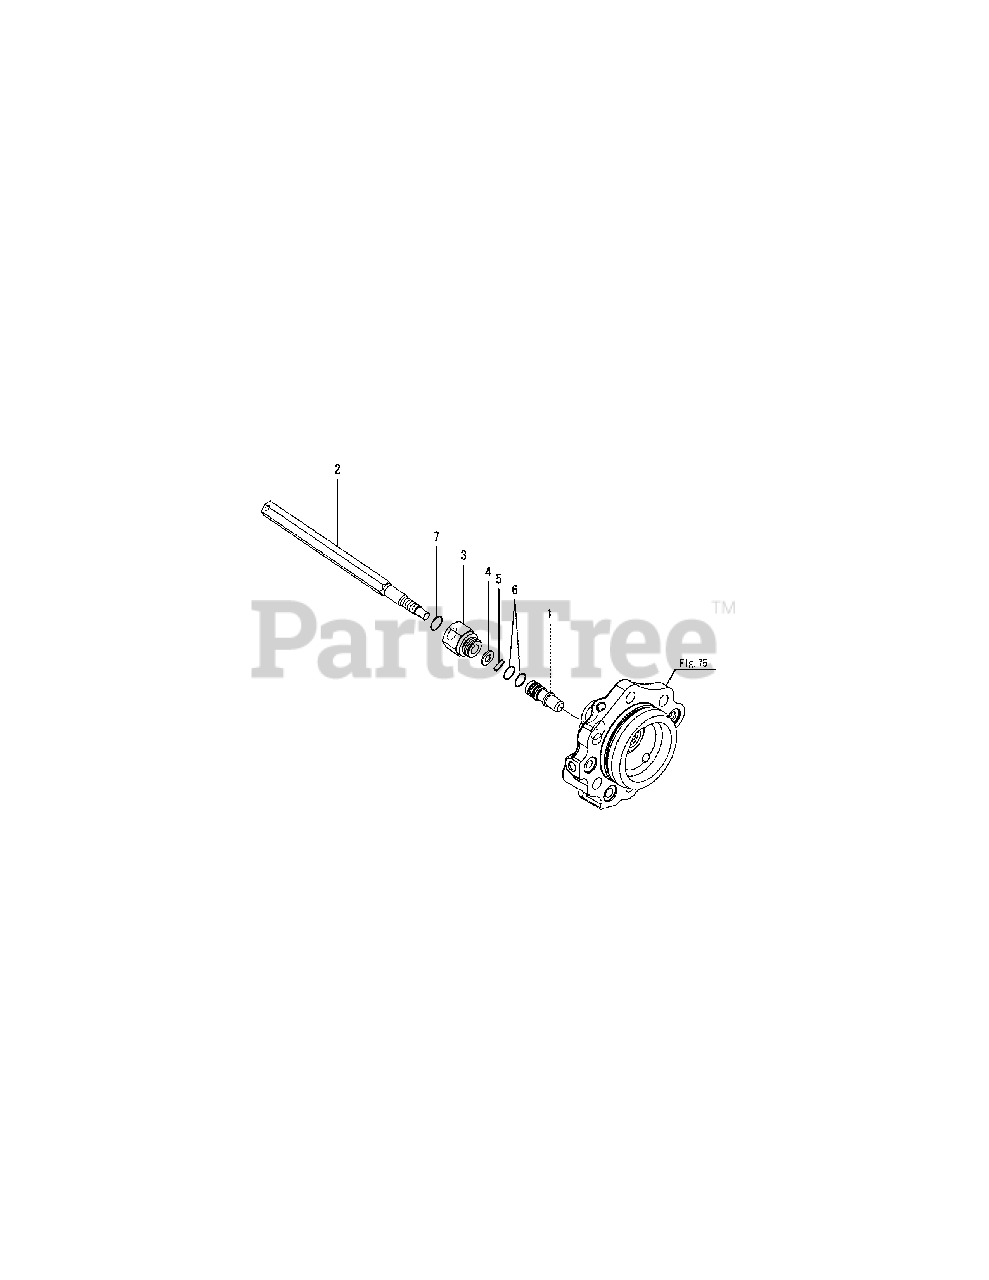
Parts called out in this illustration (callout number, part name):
5	SPRING PIN 4X12
6	O-RING 1A P-11.0
7	O-RING 1A P-12.0
